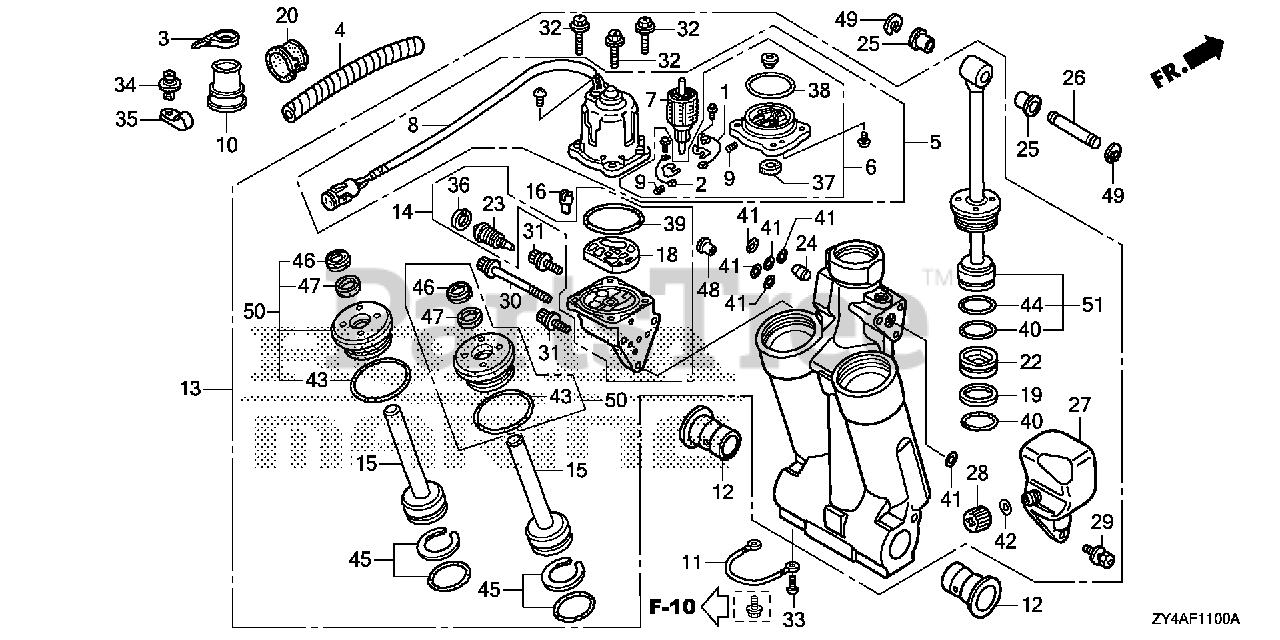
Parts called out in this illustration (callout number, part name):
1	BREAKER ASSY.
2	BRUSH ASSY.
3	BAND (BLACK 3.5X140)
4	TUBE, SPIRAL (12X14.6)
5	MOTOR ASSY., POWER TILT
6	BRACKET ASSY.
8	YOKE ASSY.
9	SPRING, MOTOR
10	GROMMET, CASE (LOWER) (C)
11	WIRE, LEAD (1.5X116MM)
12	BUSH, SWIVEL CASE
13	TRIM-TILT ASSY., POWER
14	PUMP ASSY.
15	ROD, PISTON (B)
16	JOINT, DRIVE
19	RING, BACK-UP
20	BUSH, MOTOR CODE
22	PISTON, FREE
23	VALVE, MANUAL
24	VALVE, RESERVOIR
25	BUSH, CYLINDER (LOWER)
26	PIN, CYLINDER (UPPER)
27	TANK, OIL
28	CAP, OIL TANK
29	BOLT, RECESSED
30	BOLT A, SOCKET
31	BOLT B, SOCKET
32	BOLT, HEX.
33	SCREW, PAN (6X8)
34	SCREW, RIVET (5X10)
35	CLIP (10.7MM)
36	CIRCLIP (INNER)
38	O-RING (2.0X70.5)
39	O-RING (1.8X69.6)
40	O-RING (3.5X38.7)
41	O-RING (1.8X7.7)
42	O-RING (1.9X11)
43	O-RING (3.5X35.7)
44	O-RING (3.5X41.7)
45	O-RING SET (3.5X31.7)
46	SEAL, WATER
48	COLLAR, ORIFICE
49	E-RING (15MM)
50	GUIDE, ROD
51	ROD, PISTON
